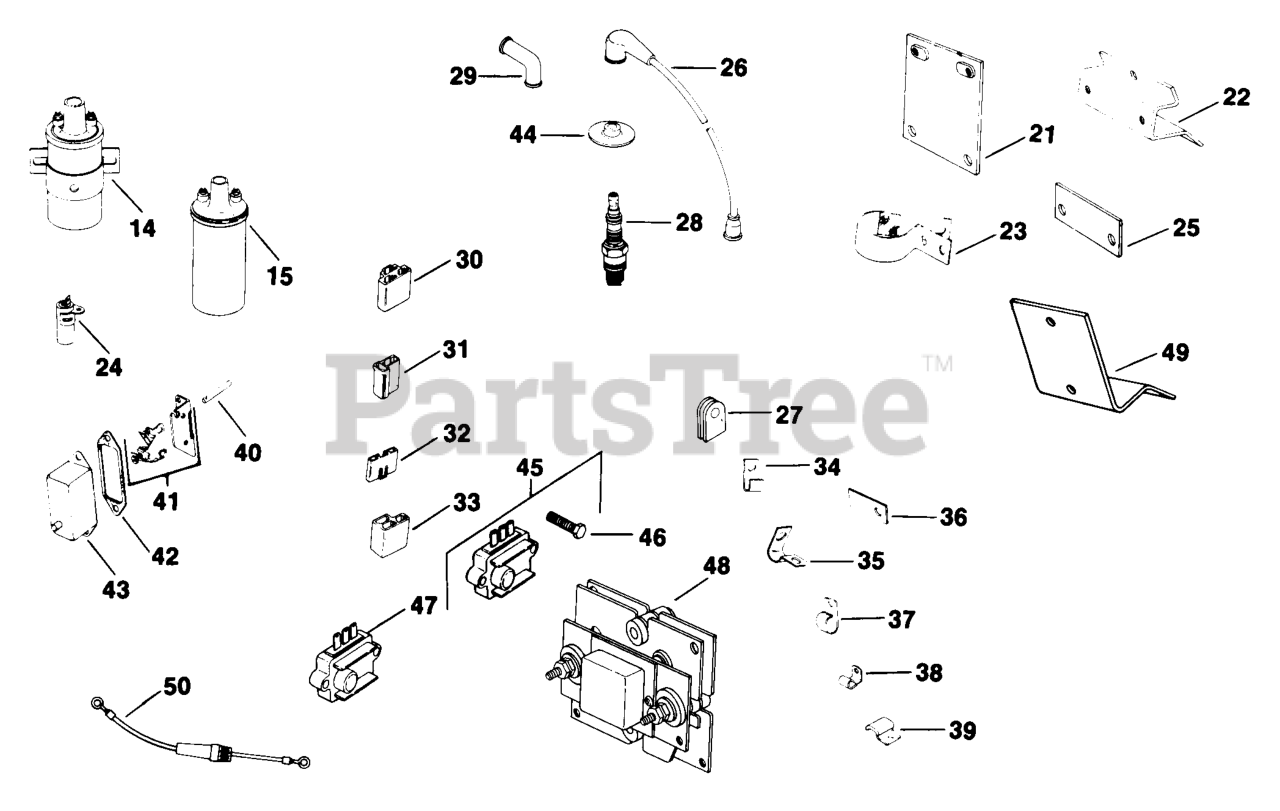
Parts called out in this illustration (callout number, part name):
24	CONDENSER
27	GROMMET
29	BOOT - (#DSC)
35	CLIP - USE 210281
42	GASKET, POINT COVER
47	REGULATOR
